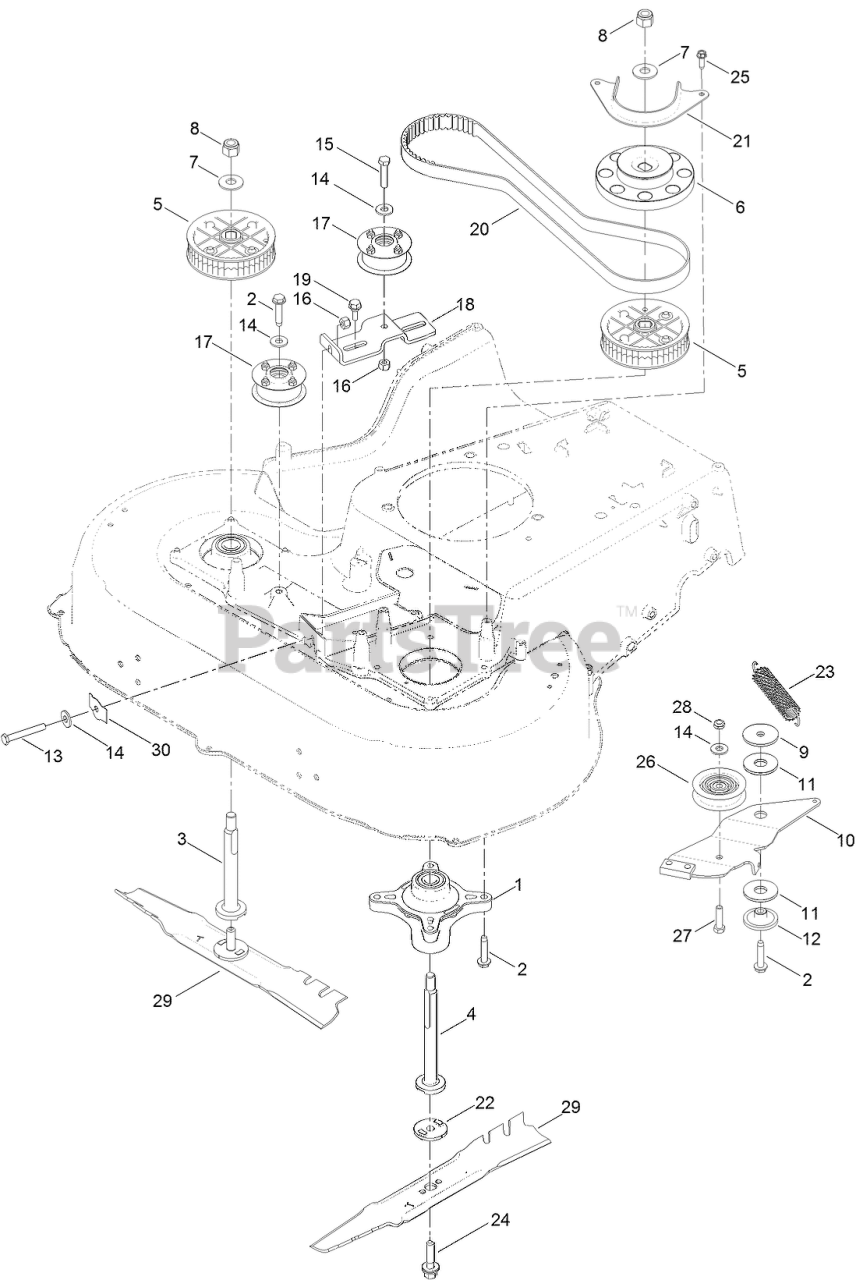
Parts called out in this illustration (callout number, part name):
1	SPINDLE ASM
3	SHAFT-SPINDLE
4	SHAFT-SPINDLE
5	SPROCKET
6	PULLEY-BRAKE, SPINDLE
7	WASHER-SPRING
8	NUT-HEX
9	WASHER-REBOUND
10	ARM-BRAKE
11	WASHER-FRICTION, COMPOSITE
12	SPACER
13	BOLT-TAP, HH
14	WASHER-FLAT
15	SCREW-HH
16	NUT-LOCK, NI
17	KIT-PULLEY
18	BRACKET-IDLER
19	SCREW-SHOULDER, HHF
20	BELT-SYNCHRONOUS
21	GUIDE-BELT, SPINDLE
22	ADAPTER-BLADE
23	SPRING-EXTENSION, BRAKE
24	BOLT-BLADE
25	SCREW-HWHTF
26	PULLEY-IDLER
27	SCREW-HH
28	NUT-LOCK, NI
29	BLADE-ATOMIC, 15.4 INCH
30	SPRING-FLAT
